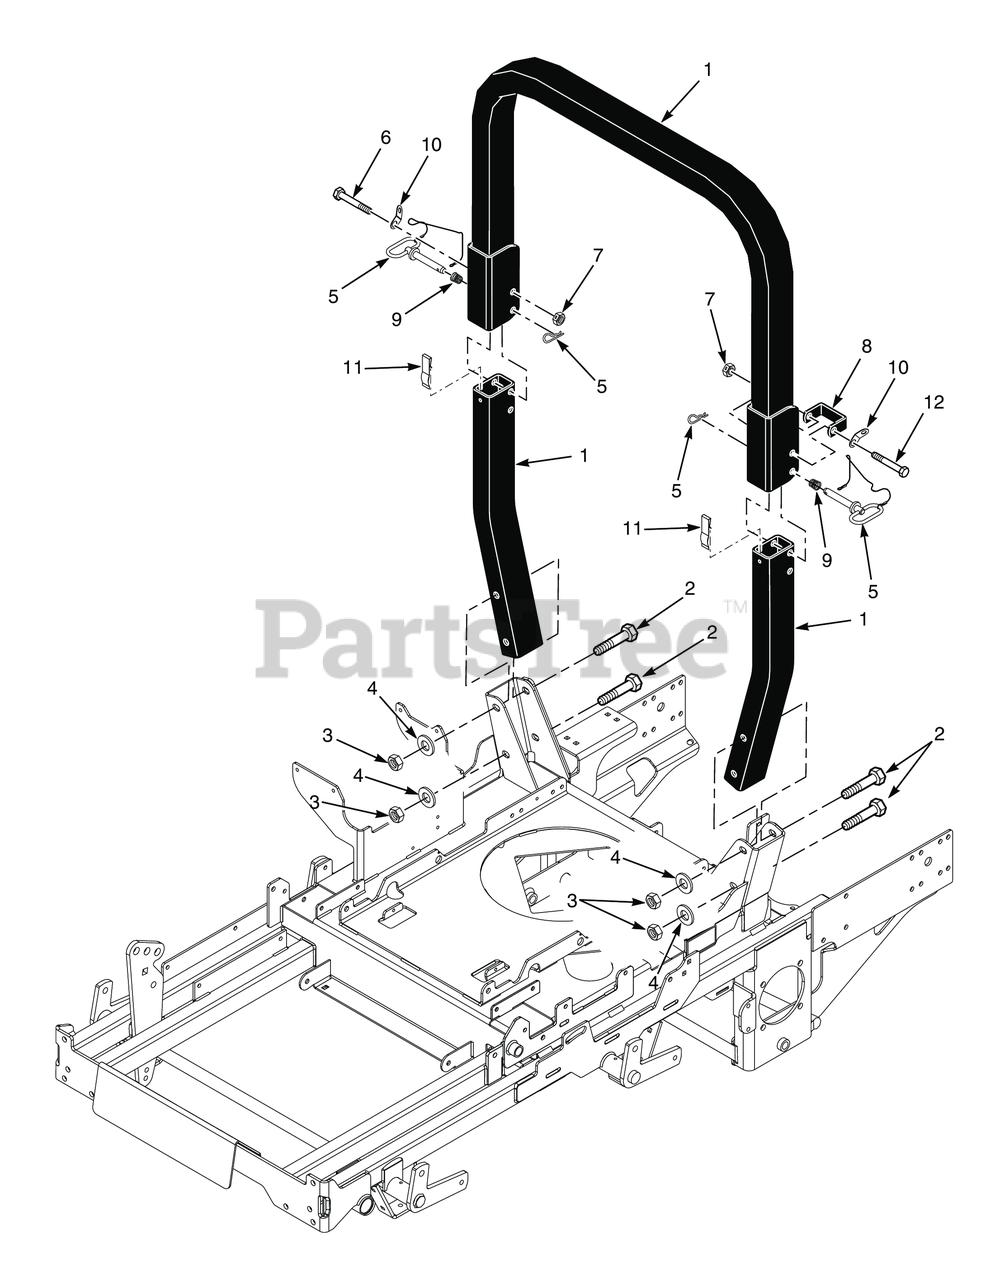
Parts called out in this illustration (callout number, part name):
1	STT, ROPS
2	Bolt, Hex Head 1/2-13 x 4-1/4"
3	Locknut, Hex 1/2-13 Center Lock
4	Flat Washer, 1/2 (.562 x 1.375 x .109)
5	Pin Assembly, ROPS Hinge
6	Bolt, Hex Head, 1/2-13 x 3-1/4"
7	HEX LOCKNUT, ELASTIC STOP, 1/2-13
8	Stop, ROPS
9	Spring, ROPS
10	Clip, ROPS
11	Spring, ROPS Anti-Rattle
12	Bolt, Hex Head 1/2-13 x 3-3/4"
